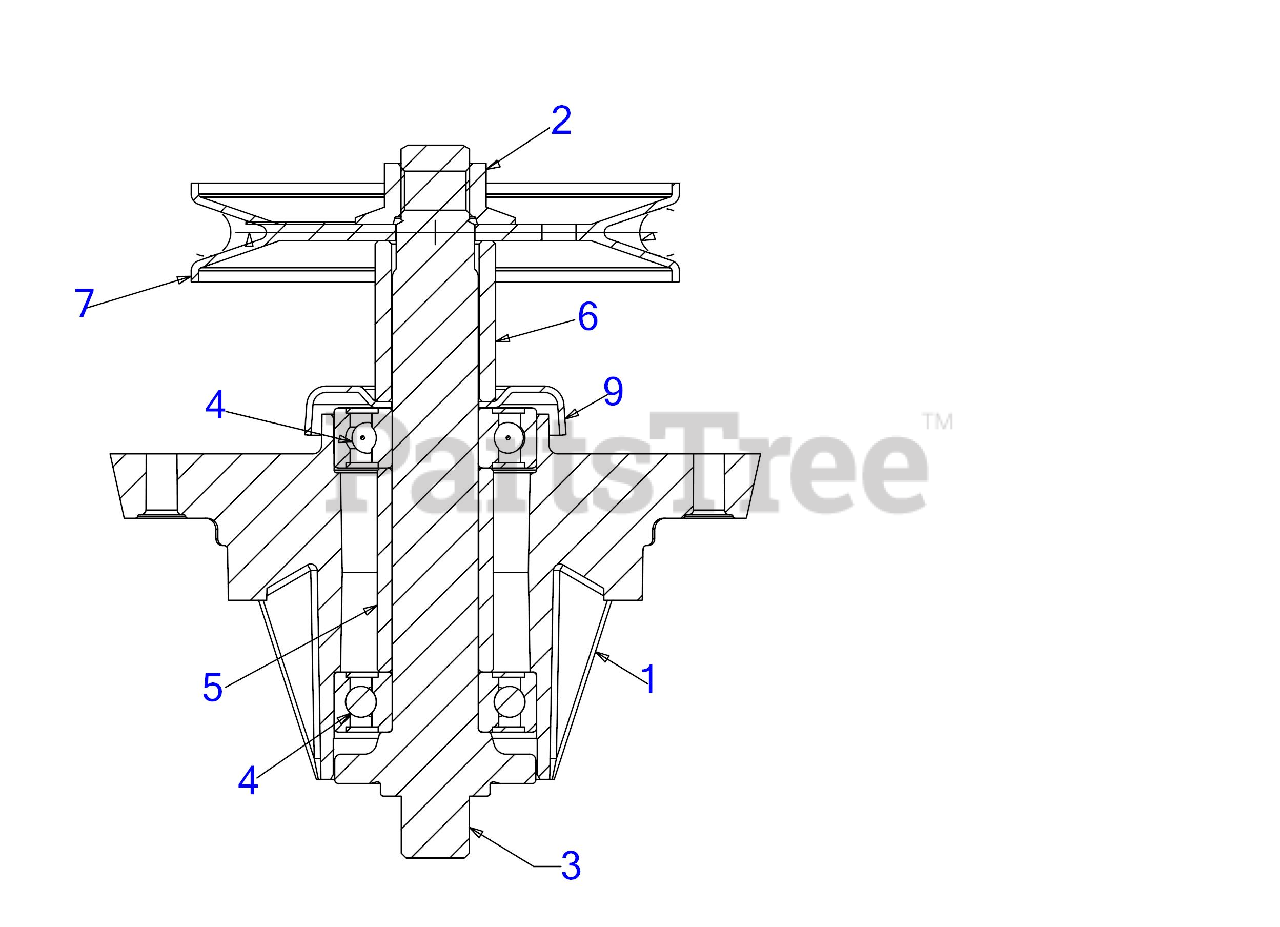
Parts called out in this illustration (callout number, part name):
1	DECK SPINDLE HOUSING
2	FLANGE NUT 5/8-18
3	SPINDLE SHAFT STAR 5.83 LG
4	BALL BEARING
5	SPACER- .792 x 1.060 x 1.860
6	SPACER .800 x 1.100 x 1.470 LG
7	DECK PULLEY 4.61" DIA
9	SHIELD-BRG DECK
